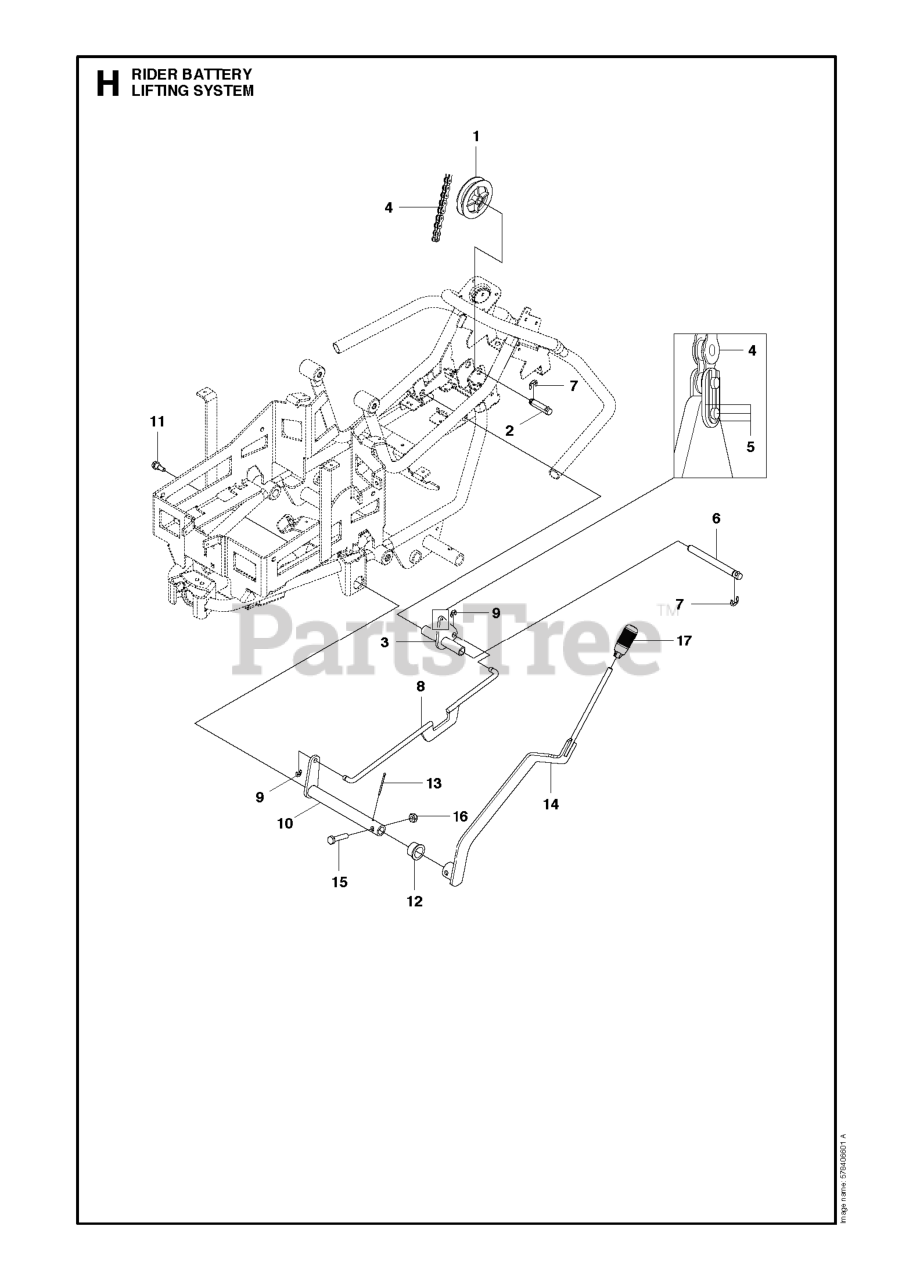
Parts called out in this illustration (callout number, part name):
9	Retaining Ring
12	BEARING FLANGE
13	COTTER PIN
15	REPL BY 725 25 00-71
16	NUT
17	GEAR STICK KNOB
